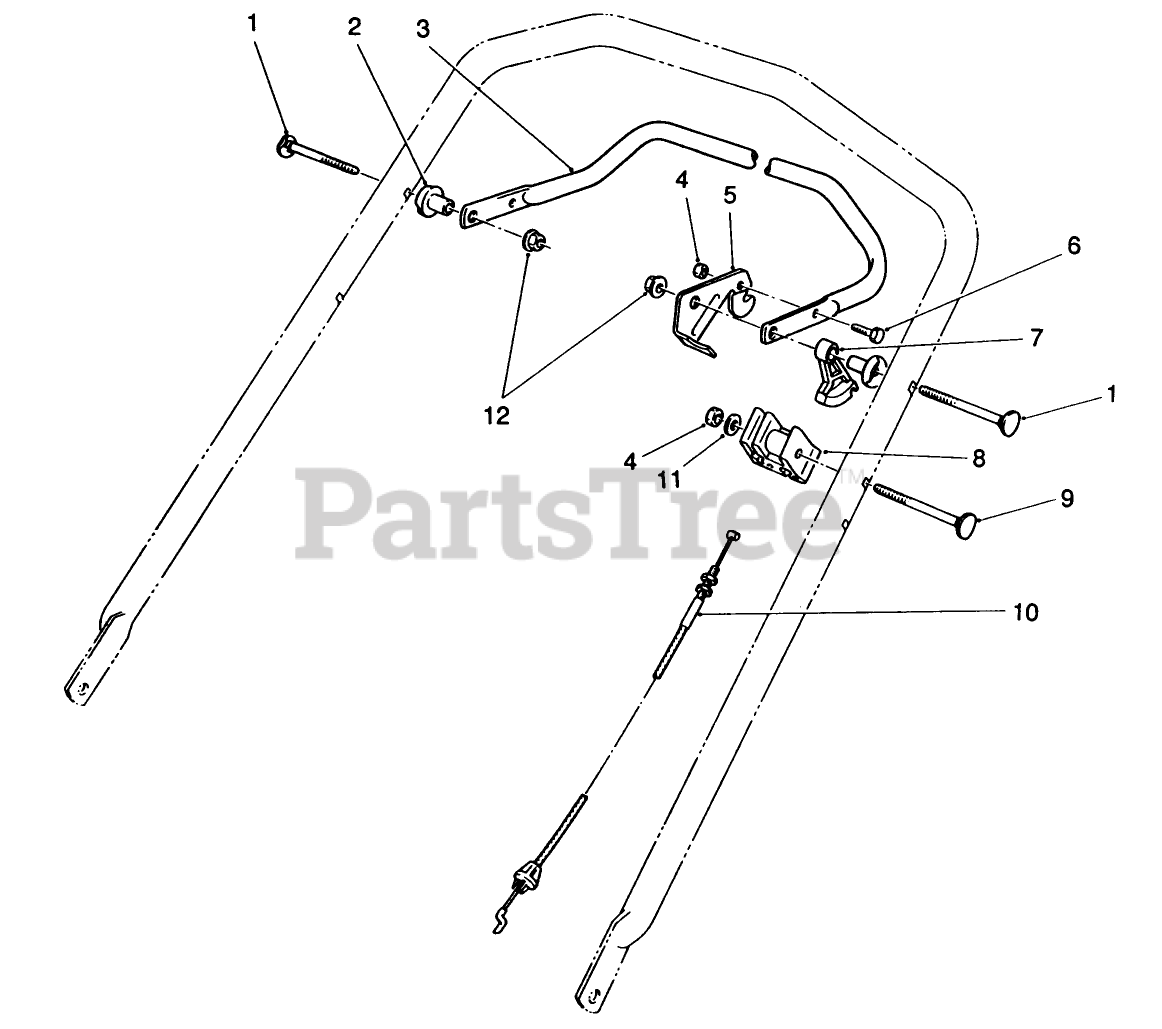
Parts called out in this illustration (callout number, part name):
1	SCREW-HANDLE
2	SPACER-SUPPORT
4	NUT-LOCK, NI
6	SCREW-HH
7	LEVER-TRACTION
8	SUPPORT-CABLE
9	SCREW-HANDLE
10	TRACTION CABLE
11	WASHER-FLAT
12	NUT-LOCK, NI
